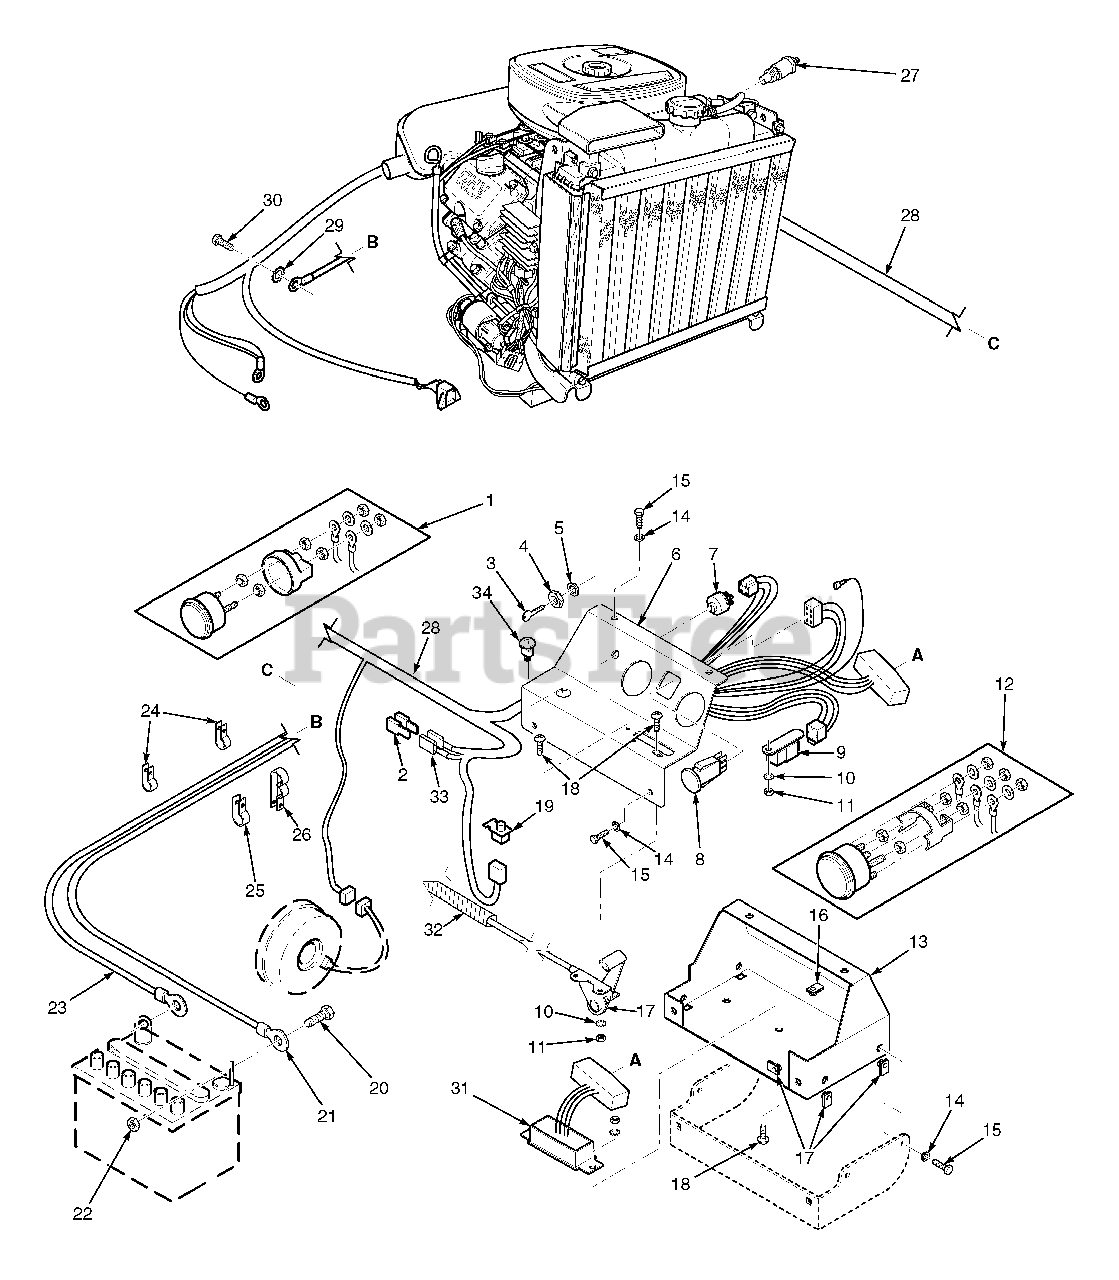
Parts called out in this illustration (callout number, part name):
1	Ammeter
2	Fuse, 20 AMP
3	Key & Ring Assembly
4	Nut, Hex 5/8-32
5	Lockwasher, 5/8" Internal
6	Instrument Panel, Top w/Decals
7	Key Switch
8	Switch, PTO
9	Relay
10	Lockwasher, #10 External Tooth
11	Nut, Hex #10-32
12	Water Temp. Gauge
13	Base, Instrument Panel
14	Lockwasher, 1/4"
15	Bolt, Hex Head 1/4-20 x 3/4"
16	U-Nut, 1/4-20
17	Throttle Controls
18	Screw, Phillips Washer Head #10-32 x 1/2"
19	Switch, Interlock-Seat
20	Bolt, Hex Head 1/4-20 x 1/2"
21	Cable, Battery - Red
22	Nut, Hex 1/4-20
23	Cable, Battery - Black
24	Clamp, Cable 1/2" ID.
25	Clamp, Cable 3/4" ID.
26	Clamp, Cable
27	Sending Unit, Water Temp.
28	Wire Harness, STT Liquid Cooled Digital Fuel Injection (DFI)
29	Lockwasher, 5/16" External Tooth
30	Bolt, Hex Head M8-1.25 x 20
31	Electronic Module
32	Heatshield, Flexible
33	Fuse Holder w/Fuse and Connector
34	Indicator Light, Check Engine
